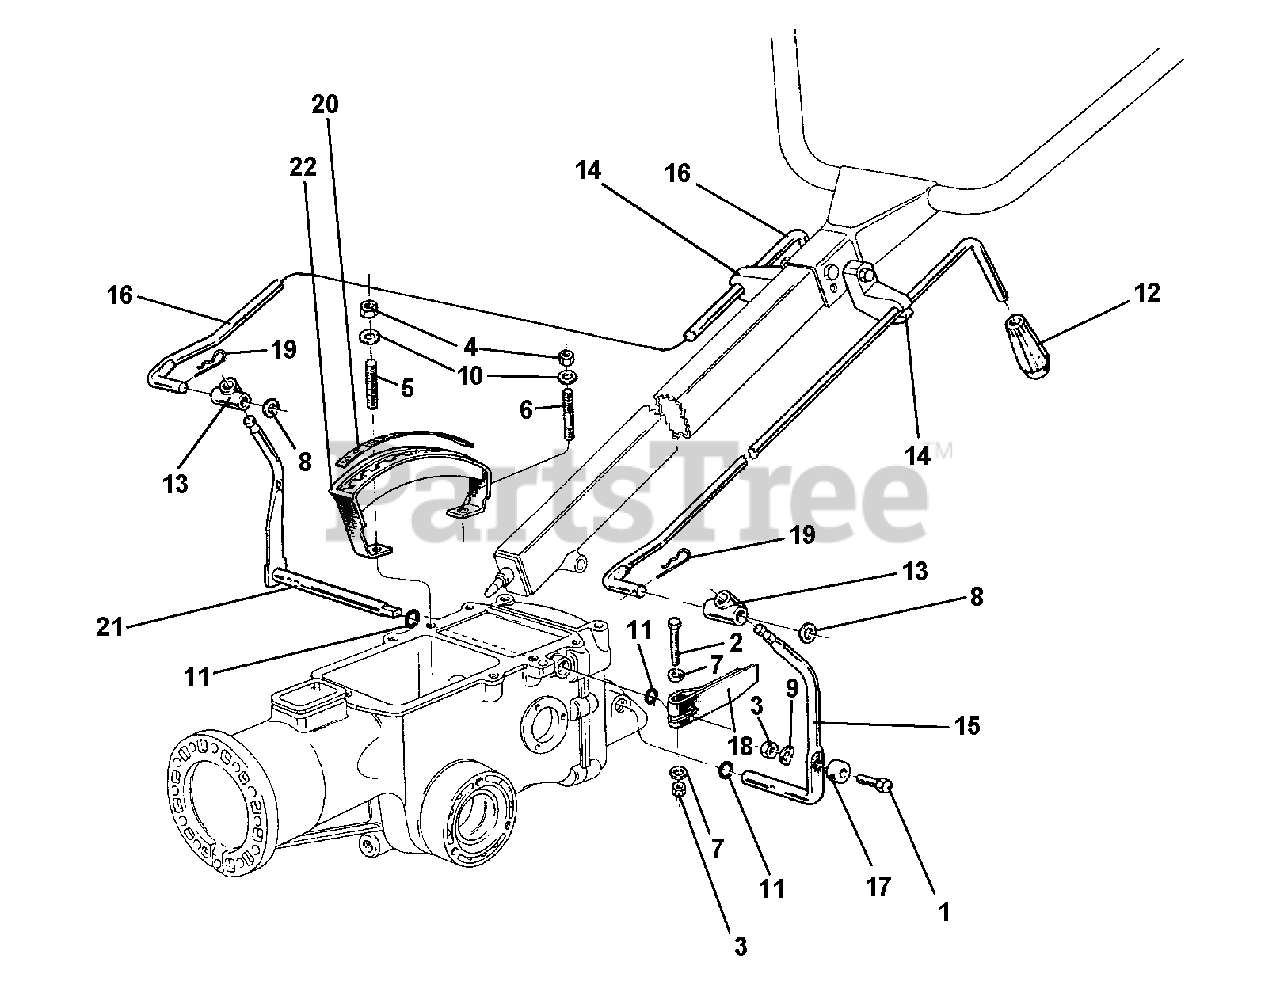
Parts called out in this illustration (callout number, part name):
1	SCREW M6 X 25
2	SCREW M6 X 40
4	NUT, SELF LOCKING M8
5	STUD M8 X 38 X 14 X 20
6	STUD M8 X 46 X 16 X 16
7	WASHER, FLAT 6.4
8	WASHER P10.5 X 18
9	WASHER, LOCK 6.4
10	WASHER, LOCK 8.4
11	O-RING 115 11.91 X 2.62
13	JOINT, D 10
14	SUPPORT CONTROL ROD CUT
15	P.T.O. LEVER
16	ROD, CONTROL POWER TILLER
18	PTO LOCKOUT
20	PLATE, 5 SPEEDS WALKING TRAC
21	GEARBOX LEVER
